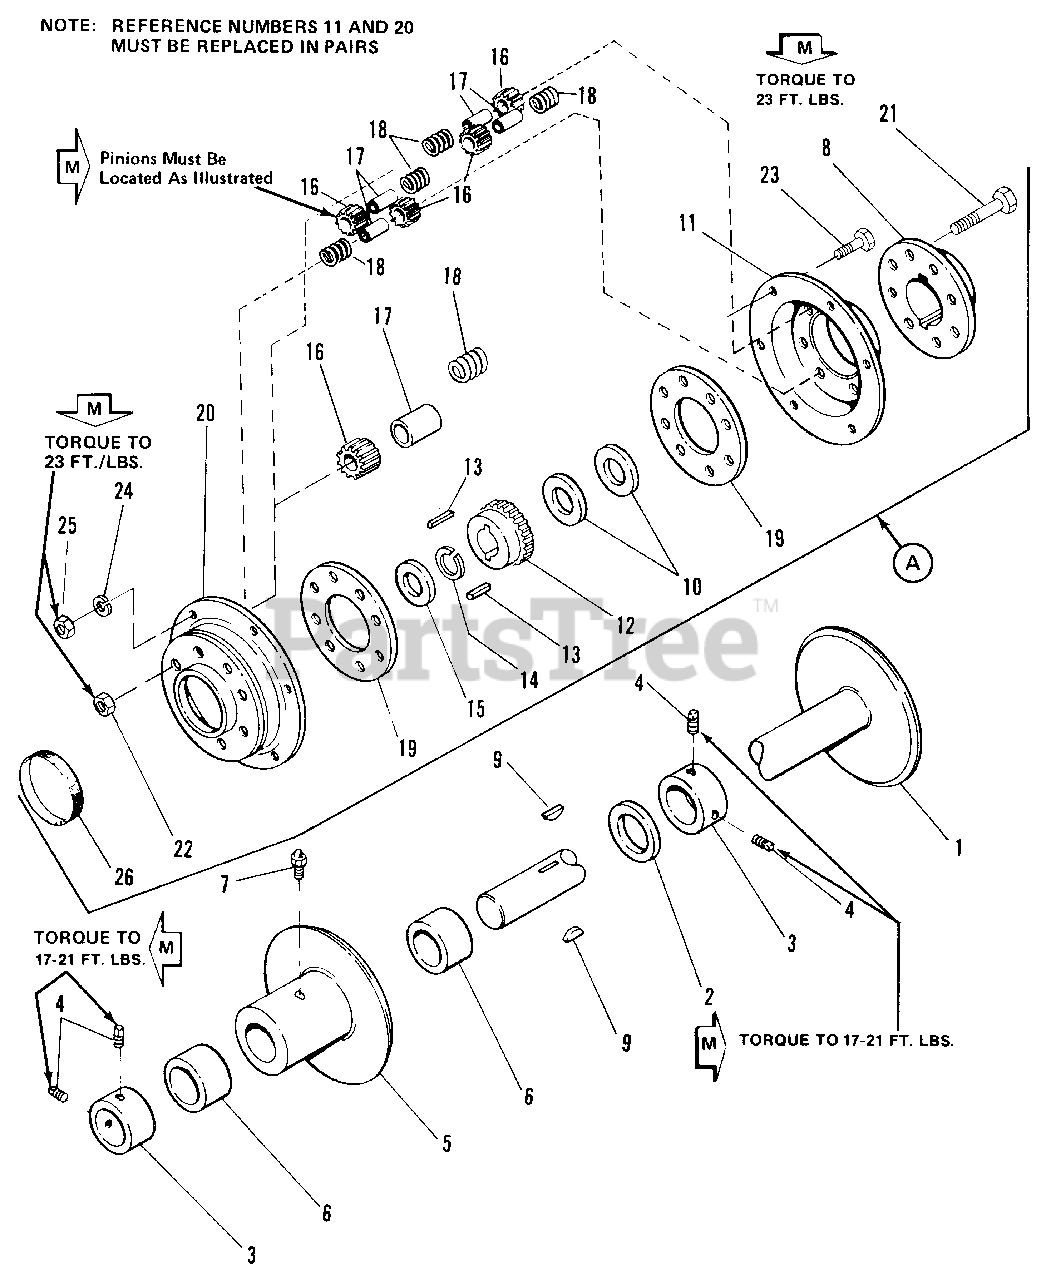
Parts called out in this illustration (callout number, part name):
1	REAR AXLE ASSEMBLY
3	COLLAR, Set
4	SETSCREW, Sq. Hd., 5/16-18 x 3/8
5	R.H. WHEEL HUB ASSEMBLY
7	FITTING, Grease
8	CARRIER, Diff.
10	WASHER, Axle
11	COVER, Diff.
12	GEAR, Diff.
13	KEY, Hi Pro, 1/4 x 3/4
14	RING, Retaining
15	WASHER, Axle
16	PINION, Diff.
17	SPINDLE, Diff. Pinion
19	RING, Spacer
20	COVER, Diff.
21	CAPSCREW, Hex Hd., 3/8-16 x 2-1/2
22	NUT, Hex, 3/8-16
23	CAPSCREW, Hex, 1/4-20 x 5/8
24	LOCKWASHER, 1/4
25	NUT, Hex, 1/4-14
26	SEAL, Cover
